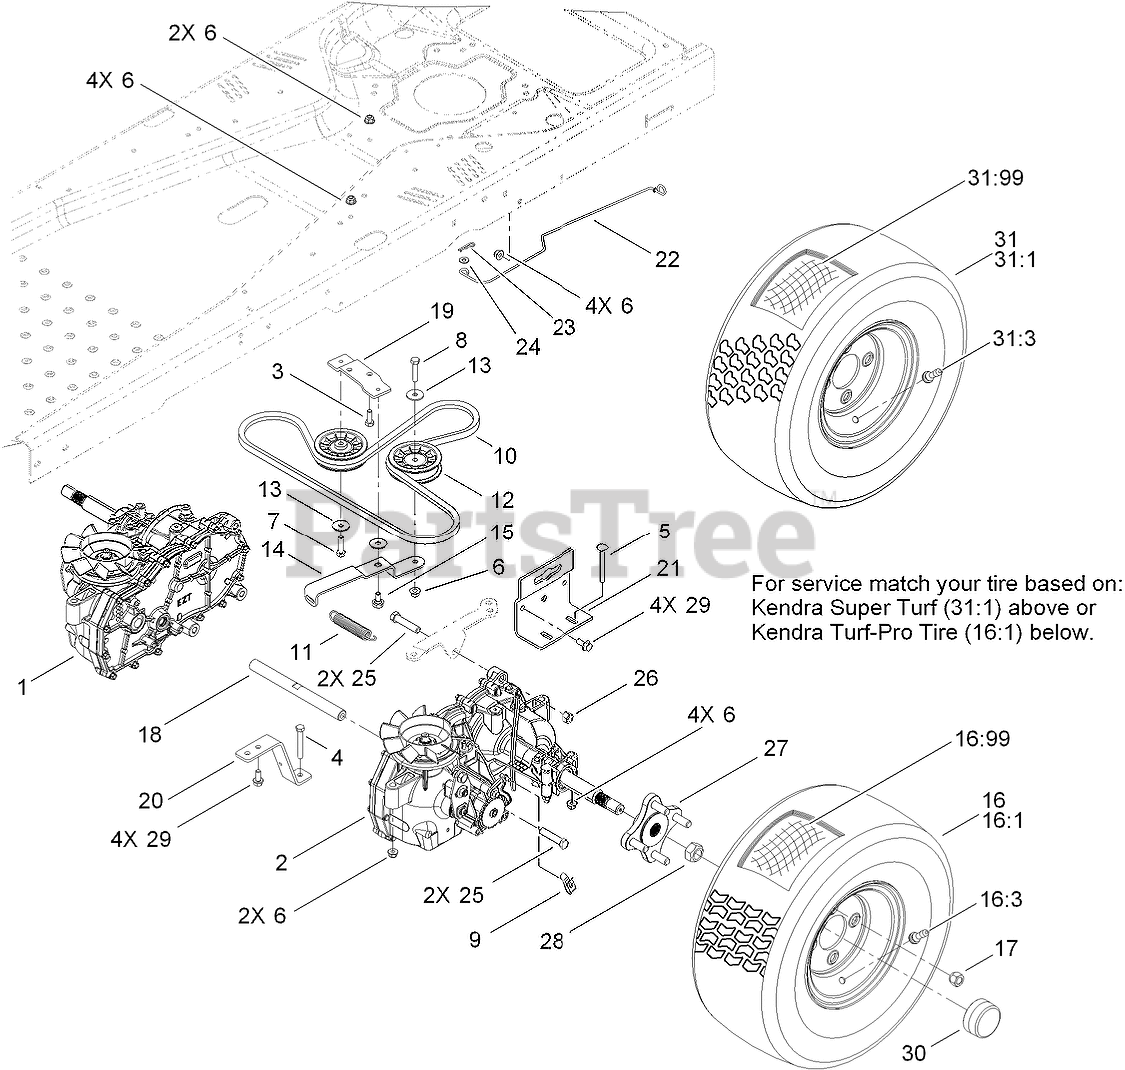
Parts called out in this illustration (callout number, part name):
1	HYDRO-RH
2	HYDRO-LH
3	SCREW-HH
4	SCREW-HH
5	SCREW-CARR
6	NUT-HF, NI
7	SCREW-HH
8	SCREW-HH
9	CLIP-SPRING
10	V-BELT
11	SPRING-IDLER
12	PULLEY-IDLER
13	WASHER-PIVOT
14	ARM-IDLER
15	BOLT-SHOULDER
16	WHEEL AND TIRE ASM
16:3	STEM-VALVE
17	NUT-LUG
18	SHAFT-CROSS
19	PLATE-PIVOT
20	STRAP-TORQUE
21	SUPPORT-HYDRO
22	ROD-BYPASS
23	PIN-COTTER
24	WASHER-FLAT
25	SCREW-HH
26	NUT-LOCK, NI
27	HUB ASM
28	NUT-LOCK
29	SCREW-HHF
30	COVER-NUT, AXLE
31	Tire and Wheel ASM
31:1	TIRE
31:3	STEM-VALVE
